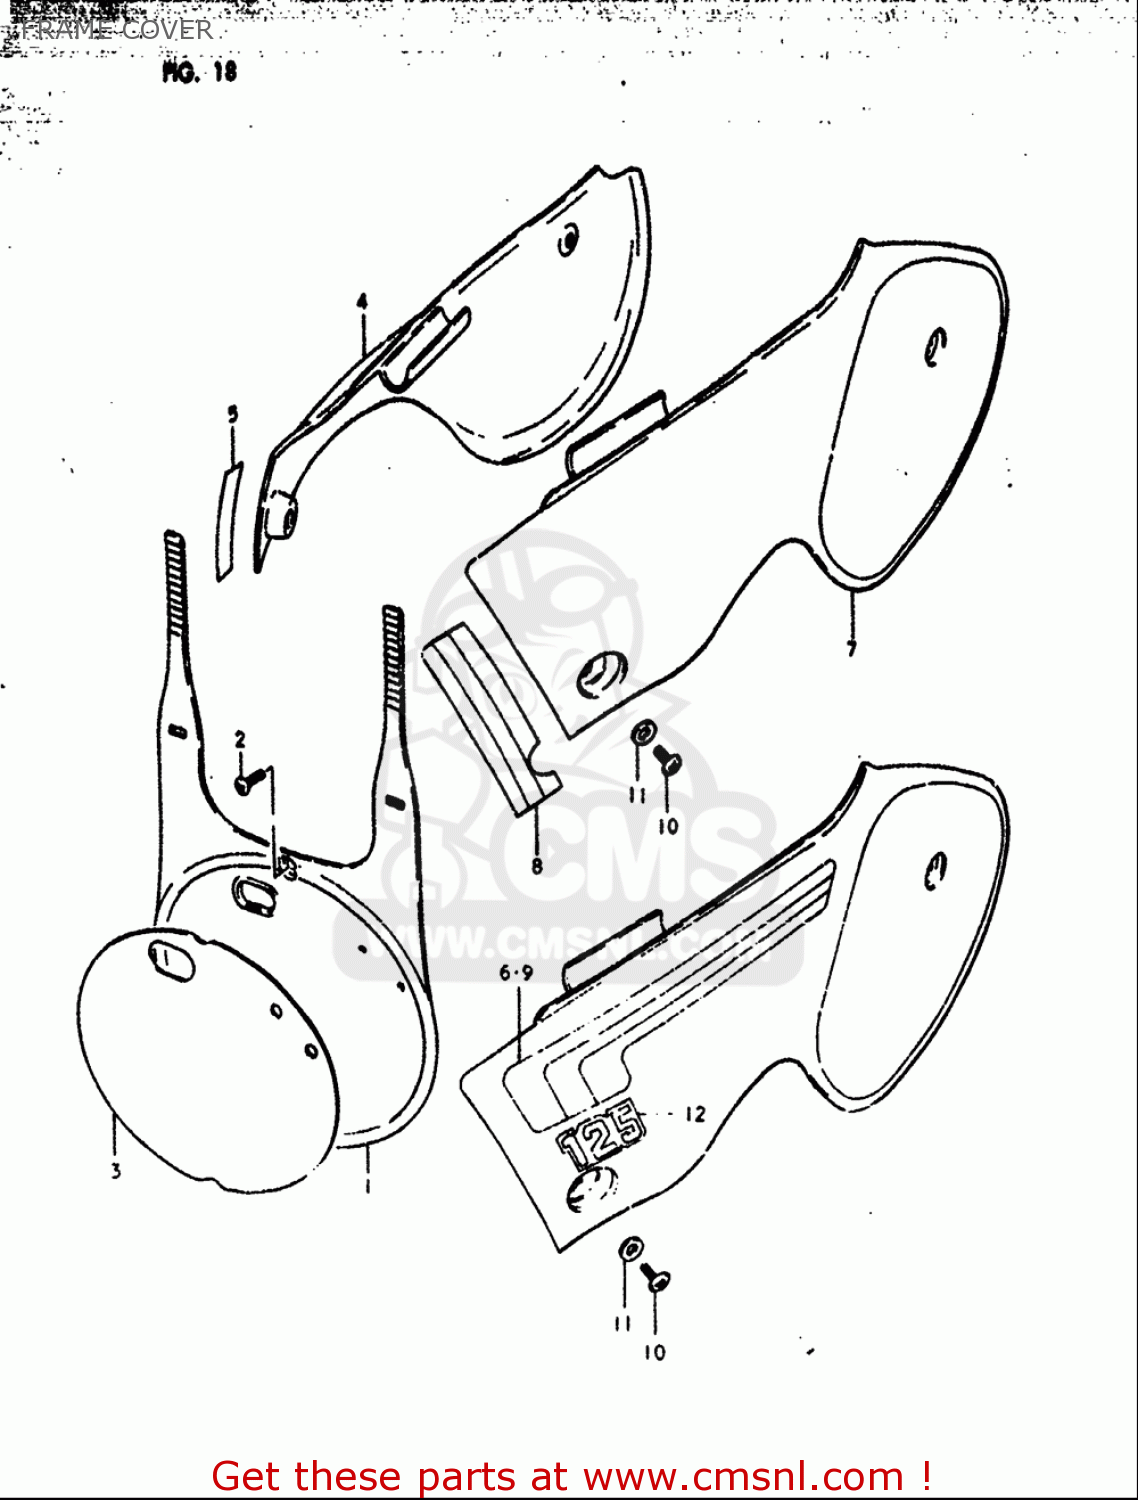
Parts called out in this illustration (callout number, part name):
1	PLATE,FR NUMBER
2	SCREW
4	COVER,FRAME(SILVER)
7	COVER,FRAME,L(YELLOW)
10	SCREW 6X12
11	WASHER(6.5X18X1.6)
